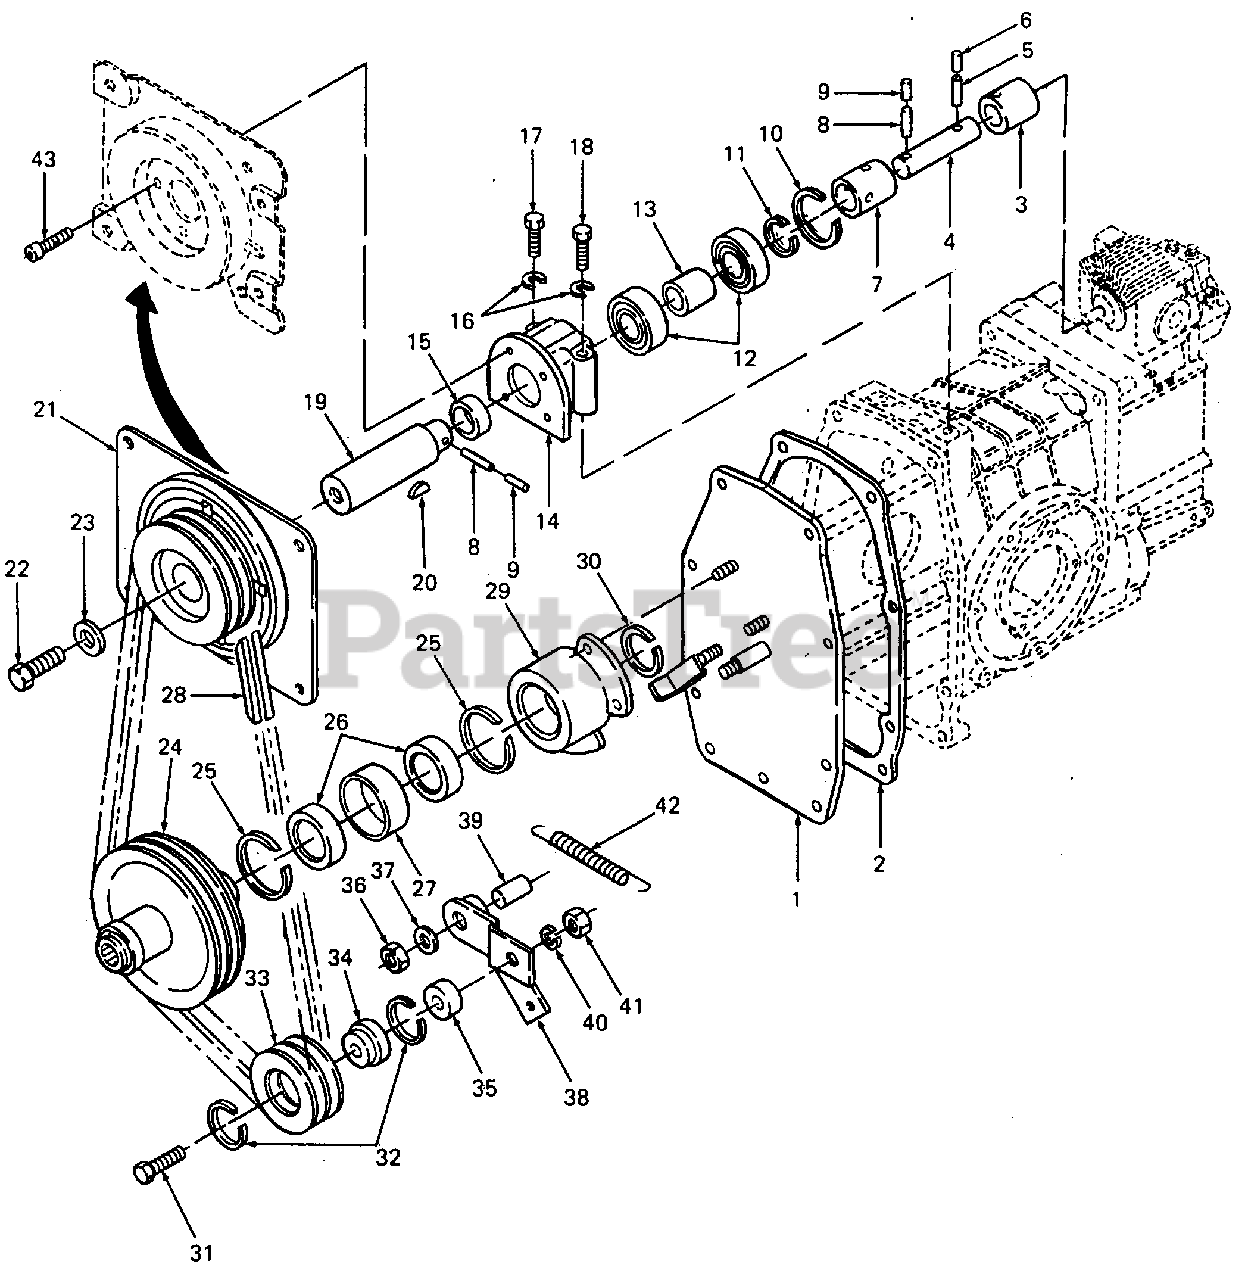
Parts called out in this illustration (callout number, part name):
1	Plate Assy, Rear Cover
2	Gasket, Rear Cover Plate
3	Coupling, Spline
4	Shaft, PTO Intermediate
5	Pin, Slotted Spring, 3/8 Dia X 1.5 Lg
6	Pin, Slotted Spring, 7/32 Dia X 1.5 Lg
8	Pin, Slotted Spring, 3/8 Dia X 2.0 Lg
9	Pin, Slotted Spring, 7/32 Dia X 2.0 Lg
10	Ring, Internal Snap
11	Ring, External Snap
12	Bearing, Ball
13	Spacer, Shaft
14	Housing, Rear Clutch Bearing
15	Spacer, Rear PTO Shaft
16	Washer, Lock, 3/8
17	Bolt, Hex Patch, 3/8-16 X 1.0 Lg GR5
18	Screw, Hex Cap, 3/8-16 X 2.75 Lg GR5
19	Shaft, Rear PTO Clutch
20	Key, #15 Woodruff, 1/4 X 1.0
21	Clutch Assy, PTO
22	Screw, Hex Cap, 3/8-16 X 1.0 Lg GR8
23	Washer, Flat, .406 ID X 1.5 OD X .094 Thk
24	Hub Assy, Double Pulley
25	Ring, Internal Snap
26	Bearing, Ball
27	Spacer, Pulley Housing
28	V-Belt, Matched Set of 2
29	Housing, Rear Pulley
30	Ring, External Snap
31	Screw, Hex Cap, 1/2-13 X 2.0 Lg GR8
32	Ring, Internal Snap
33	Pulley, Idler
35	Spacer, Pipe
36	Nut, Hex Center Lock, 3/8-16 GR5
37	Washer, Flat, .406 ID X 1.0 OD X .105 Thk
38	Bracket Assy, Idler Pulley
39	Bushing, Idler Pulley
40	Washer, Lock, 1/2
41	Nut, Hex, 1/2-13
42	Spring, Rear PTO
43	Screw, Hex Socket Hd, 1/4-20 X .50 Lg
